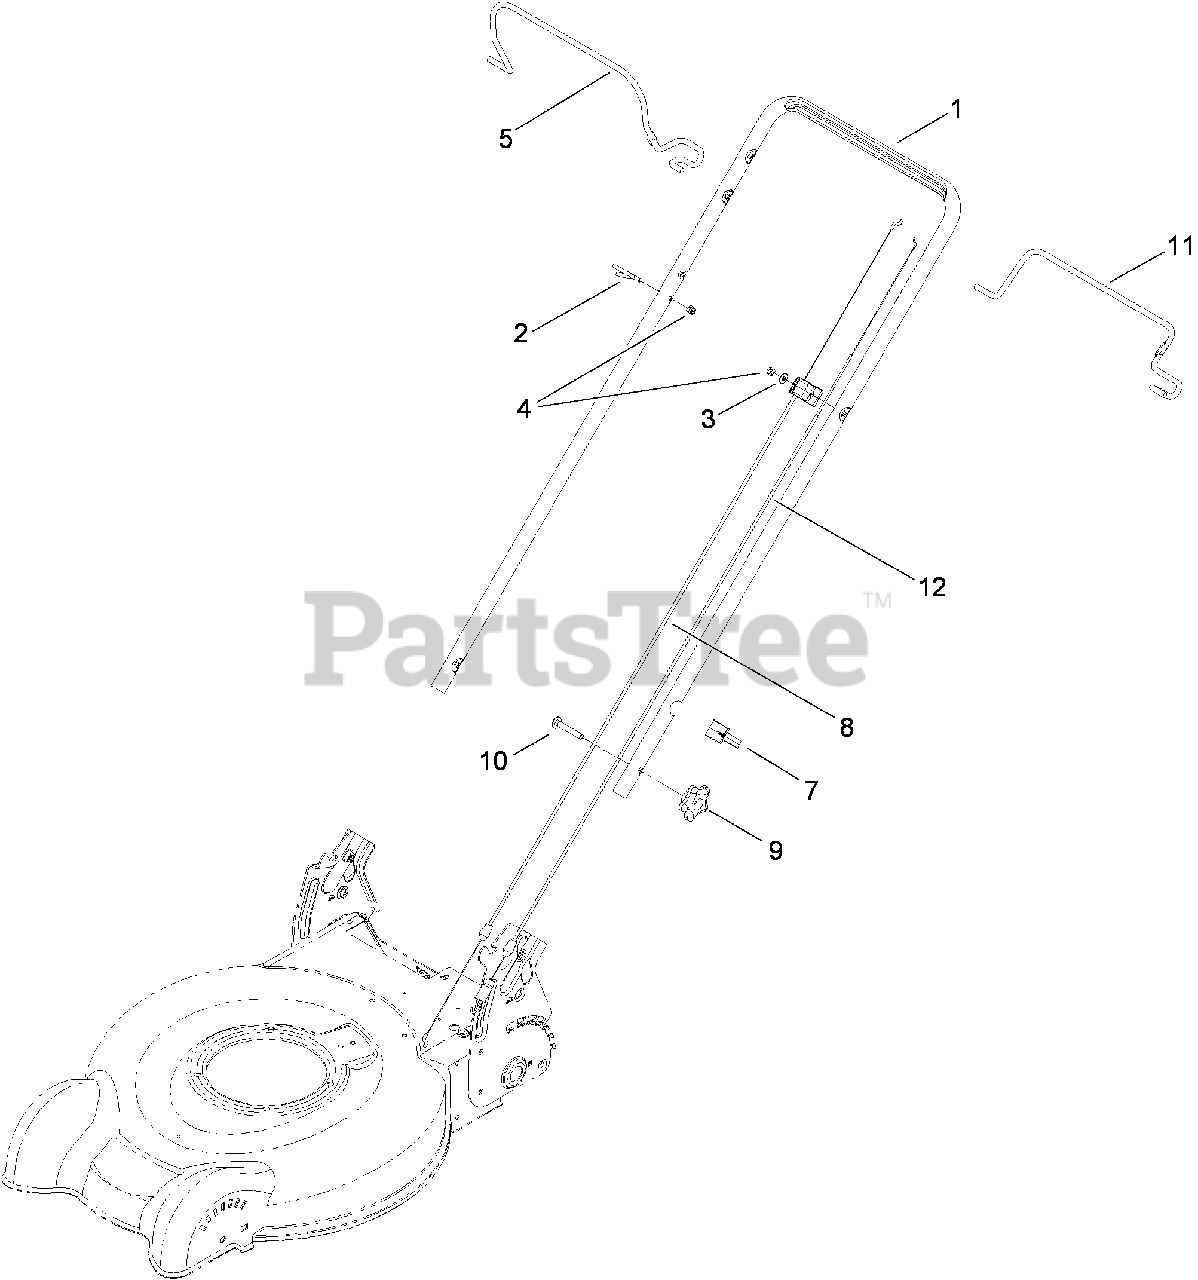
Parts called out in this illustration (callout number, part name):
1	HANDLE
2	GUIDE-ROPE
3	WASHER-FLAT
4	NUT-LOCK, NI
5	BAIL-BRAKE, 2-BAIL FLAT
7	GUIDE-CABLE
8	CABLE-BRAKE
9	KNOB-HANDLE, LOCKING
10	Screw-CARR
11	BAIL-TRACTION, 2-BAIL FLAT
12	CABLE-TRACTION
